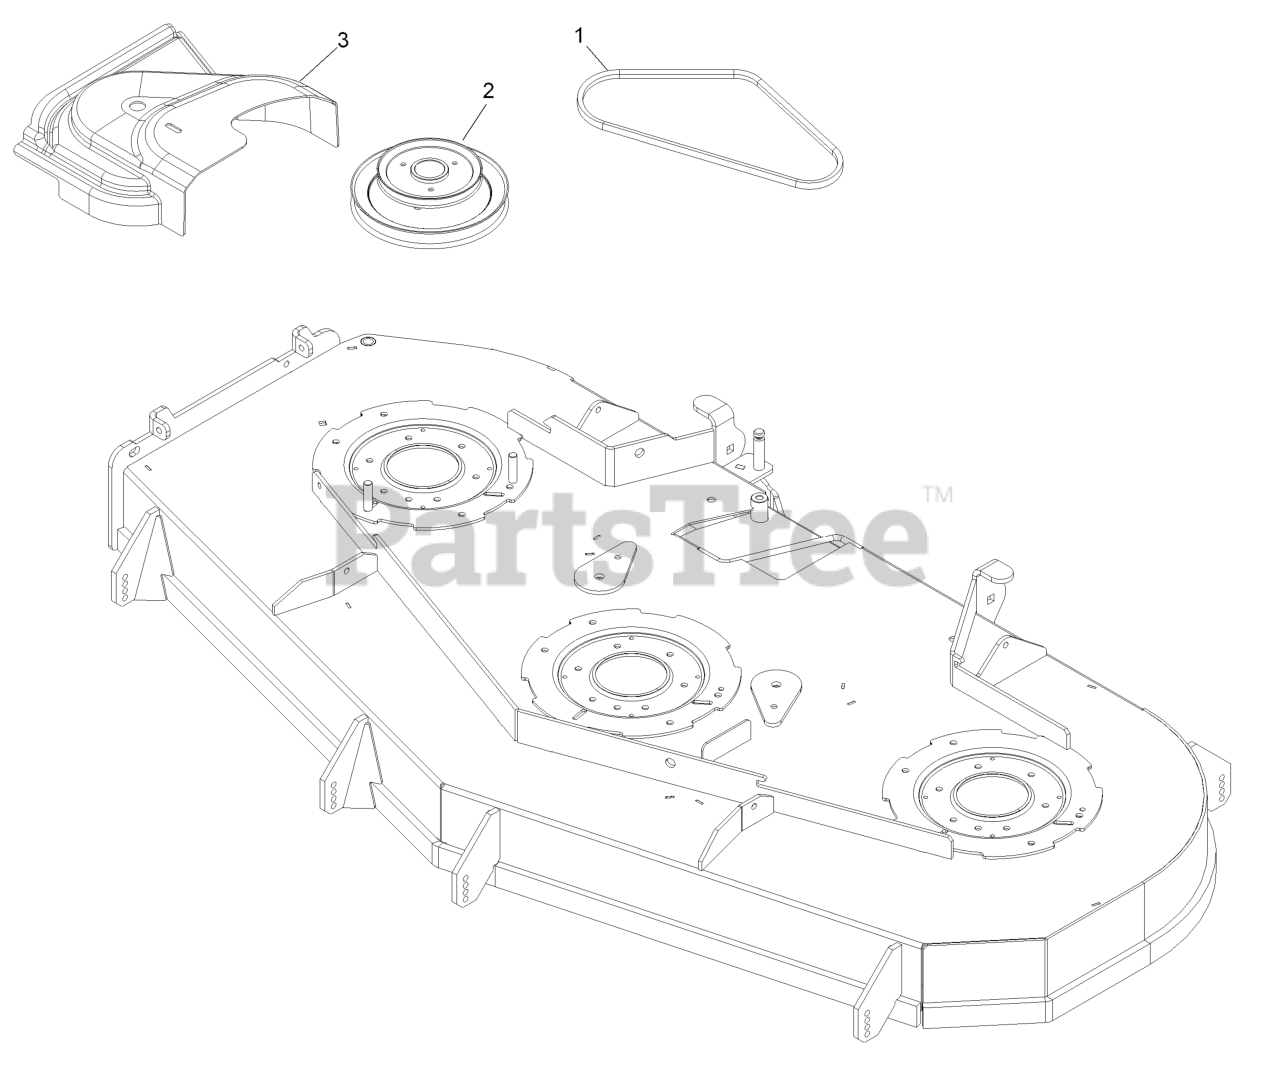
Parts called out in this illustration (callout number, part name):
1	BELT, BLOWER DRIVE 72
2	JACKSHAFT,UV DRIVE 724 SPLINED
3	COVER,BELT UV 72
